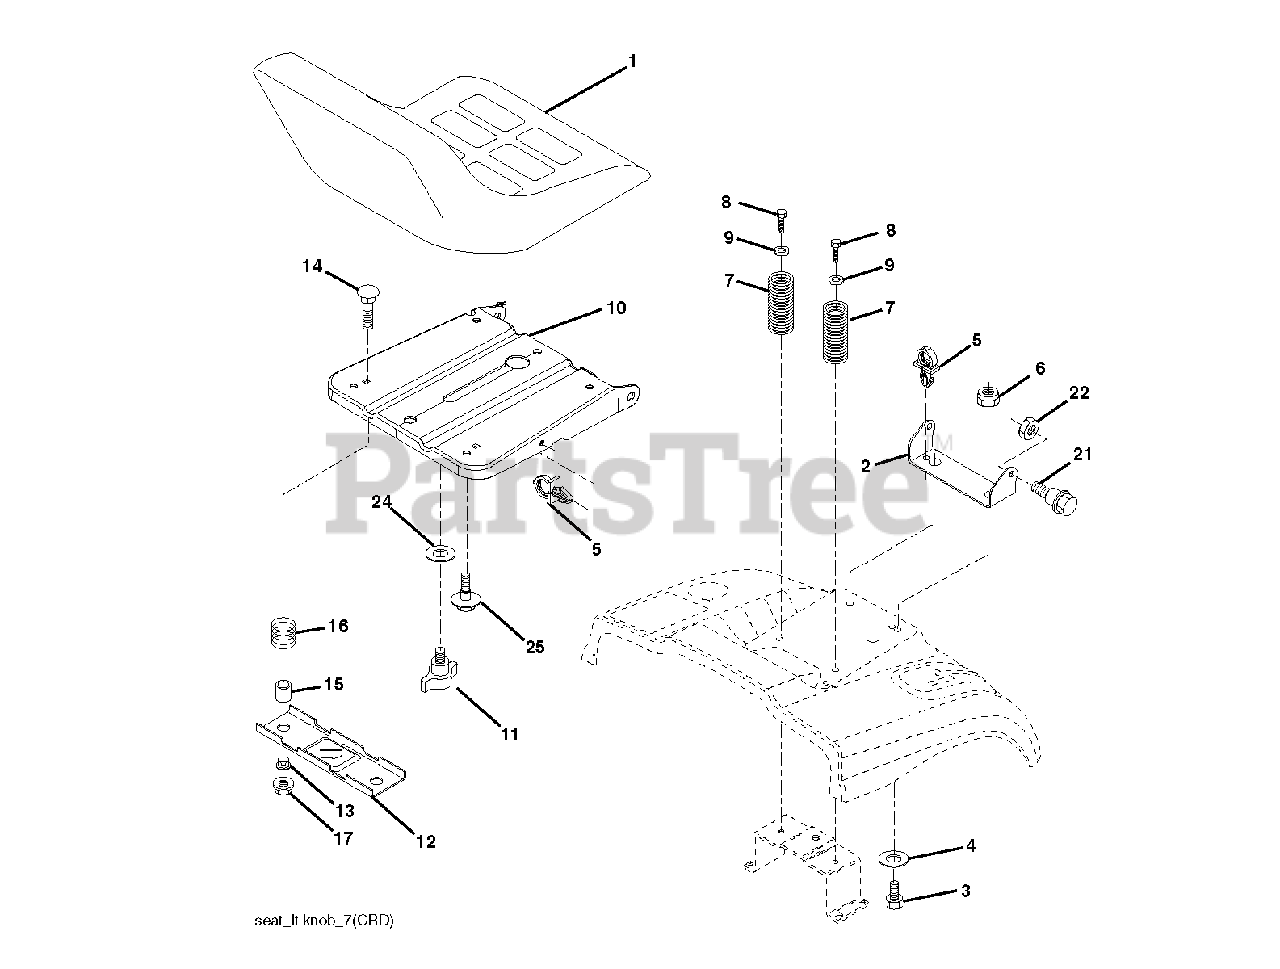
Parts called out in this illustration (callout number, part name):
1	SEAT.XG150.BLK.KB/SLD.NO-LOGO
2	SEAT PIVOT BRKT
4	WASHER PM
5	PUSH CLIP
6	NUT
7	SPRING COMPRESSION
8	SCREW 3/8-16X1
9	WASHER
10	PAN.ASM.SEAT.1SLOT
11	KNOB.SEAT.ADJ.WINGNUT
12	BRKT.MNTNG.SWITCH.SEAT
14	BOLT.ROUND.HEAD.SQUARE.NECK
15	SPACER SPLIT
16	SPRING COMPRESSED
17	NUT T
21	BOLT.SHOULDER.5/16-18
22	NUT.71038.31-18.HEX.NYLOCK
25	BOLT,SHOULD
